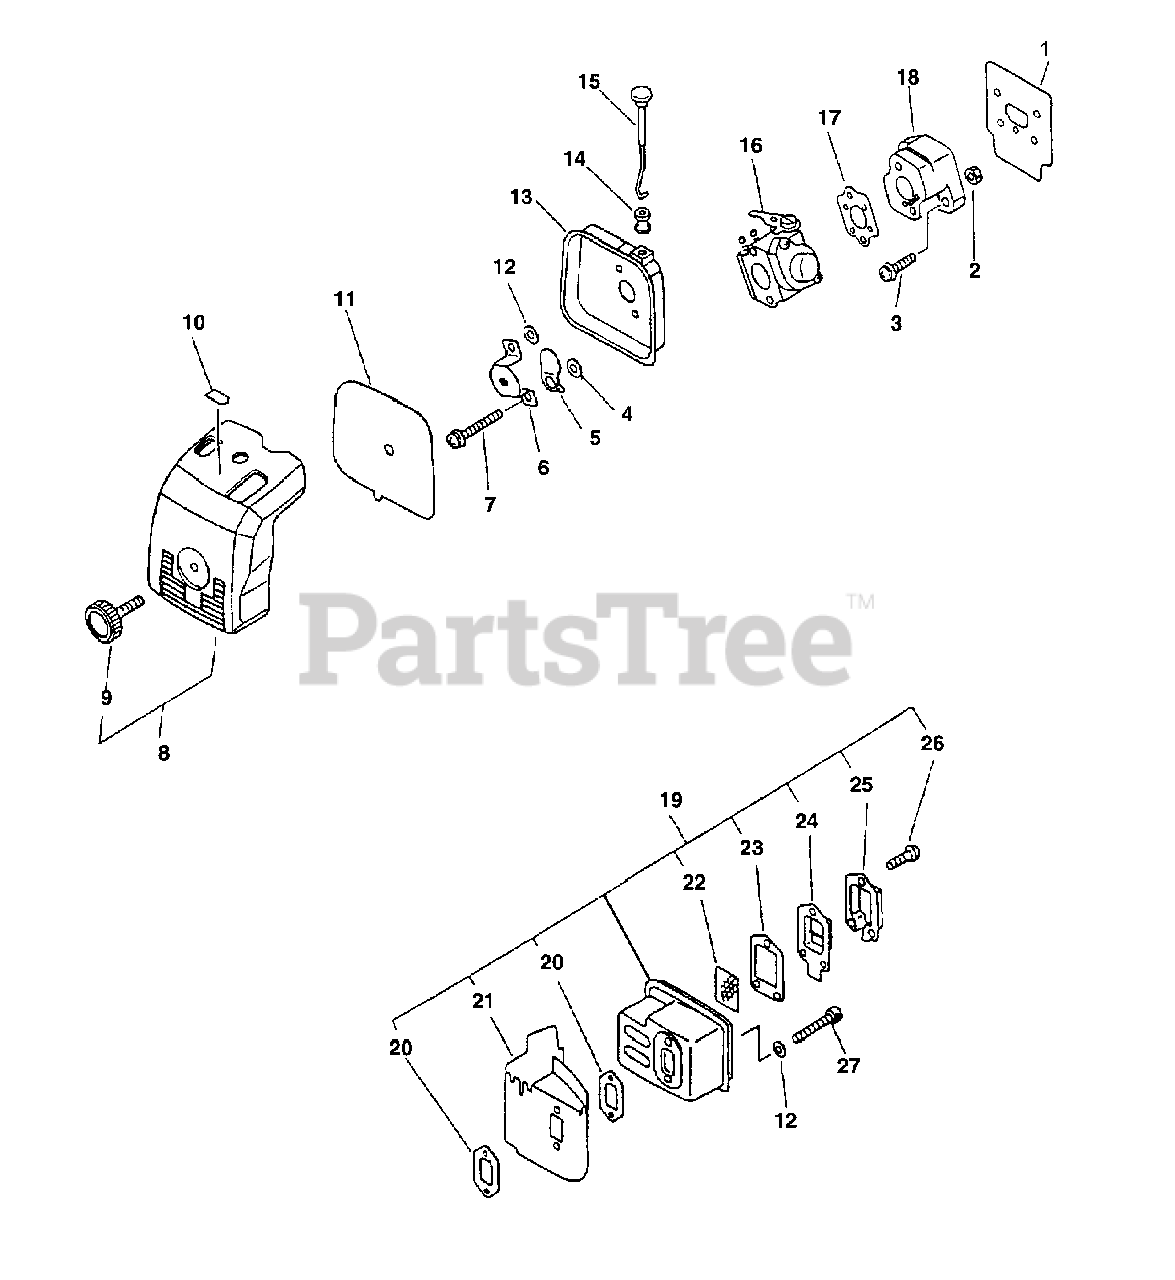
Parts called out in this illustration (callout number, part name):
1	SHIELD, INTAKE
3	SCREW - 5X20
4	WASHER - 5
5	SHUTTER, CHOKE
6	PLATE, PREVENT
7	SCREW - 5X57
8	AIR FILTER COVER ASSY
9	THUMBSCREW
10	LABEL - CHOKE
11	FILTER, AIR - HEAVY DUTY
12	WASHER - 5
13	CASE, AIR FILTER
15	ROD, CHOKE
16	CARBURETOR WT-424A
17	GASKET, INTAKE
18	INSULATOR, INTAKE
19	MUFFLER ASSY
20	GASKET, EXHAUST
21	COVER, EXHAUST
22	SCREEN, SPARK ARRESTOR
23	GASKET, EXHAUST
24	GASKET, EXHAUST - INNER
25	GUIDE, EXHAUST - OUTER
26	SCREW - 4X10
27	SCREW - 5X55
